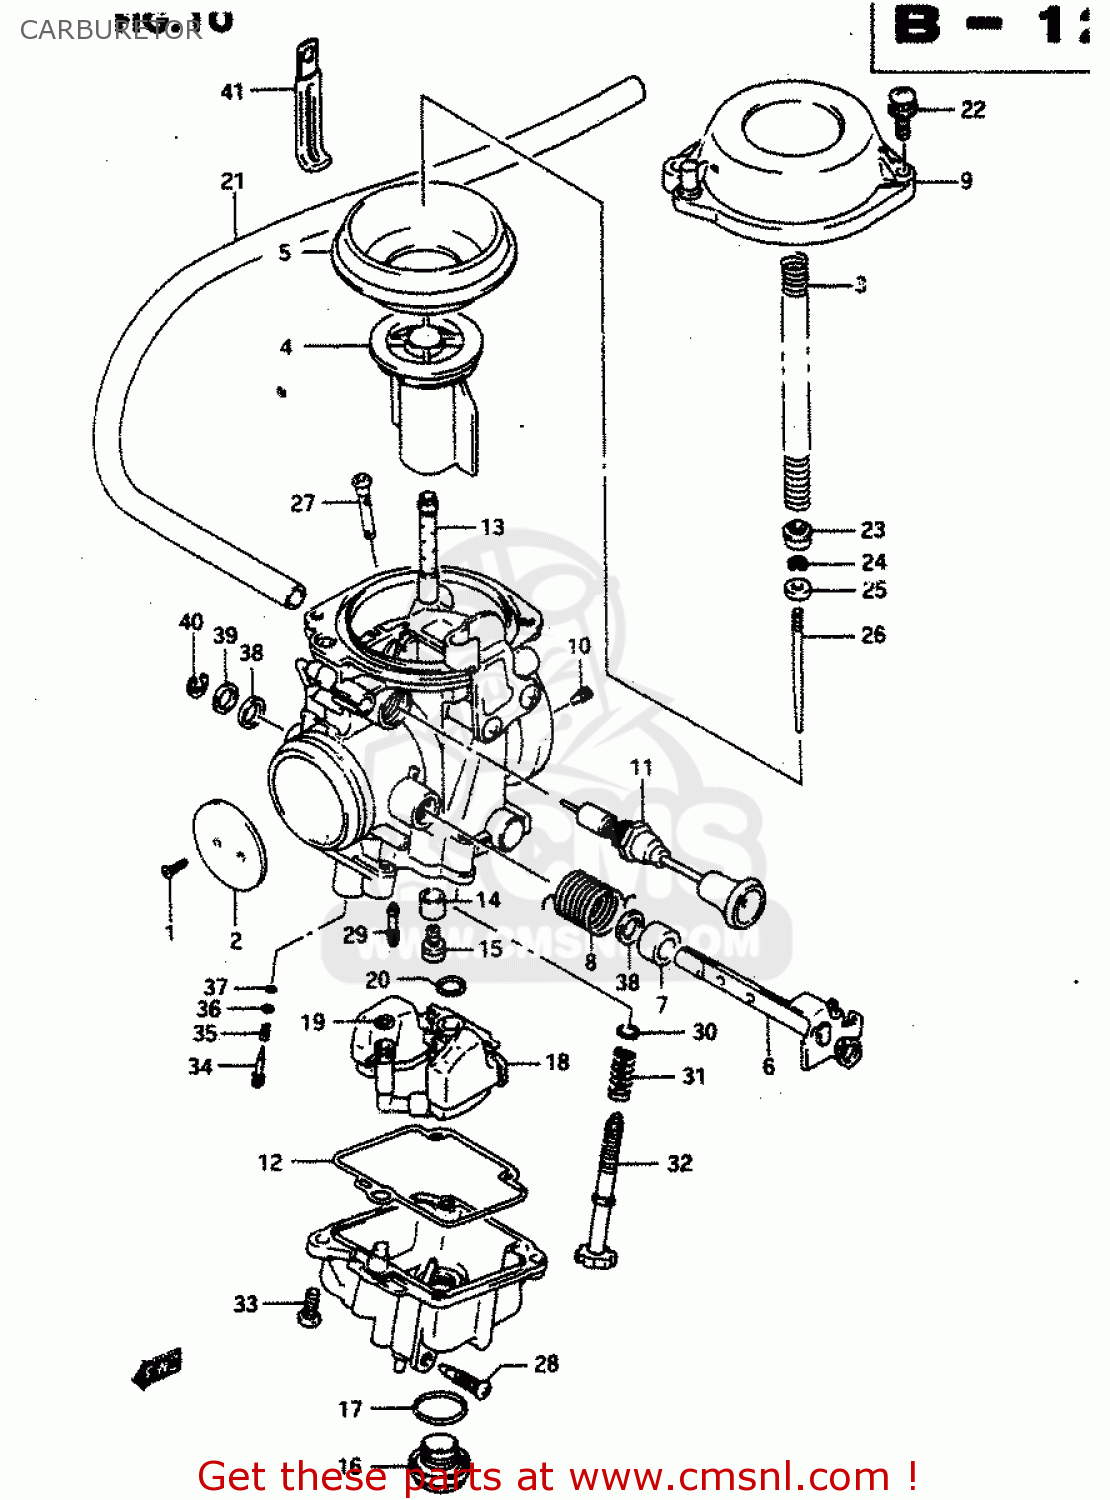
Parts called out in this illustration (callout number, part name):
1	SCREW
2	VALVE,THROTTLE
3	SPRING
4	VALVE,PISTON
5	DIAPHRAGM
6	SHAFT ASSEMBLY,THROTTLE
7	RING
8	SPRING
9	COVER,DIAPHRAGM
10	JET,AIR
11	PLUNGER ASSY
12	GASKET,FLOAT CHAMBER (NAS)
13	JET,NEEDLE
14	RING
15	JET,MAIN(142.5)
16	SCREW,GUIDE
17	O RING,DRAIN PLUG
18	FLOAT/NEEDLE VALVE ASSEMBLY
19	O RING
20	O-RING,NEEDLE VALVE
21	HOSE
22	SCREW
23	RING
24	CLIP,NEEDLE
25	RING
26	NEEDLE,JET
27	FILTER
28	PLUG,DRAIN
29	JET, PILOT (50)
30	WASHER
31	SPRING
32	SCREW
33	SCREW
34	SCREW,PILOT
35	SPRING
36	WASHER
37	O RING,PILOT AIR SCREW
38	SEAL
39	GASKET,THROTTLE SHAFT (NAS)
40	E RING
41	CLAMP
